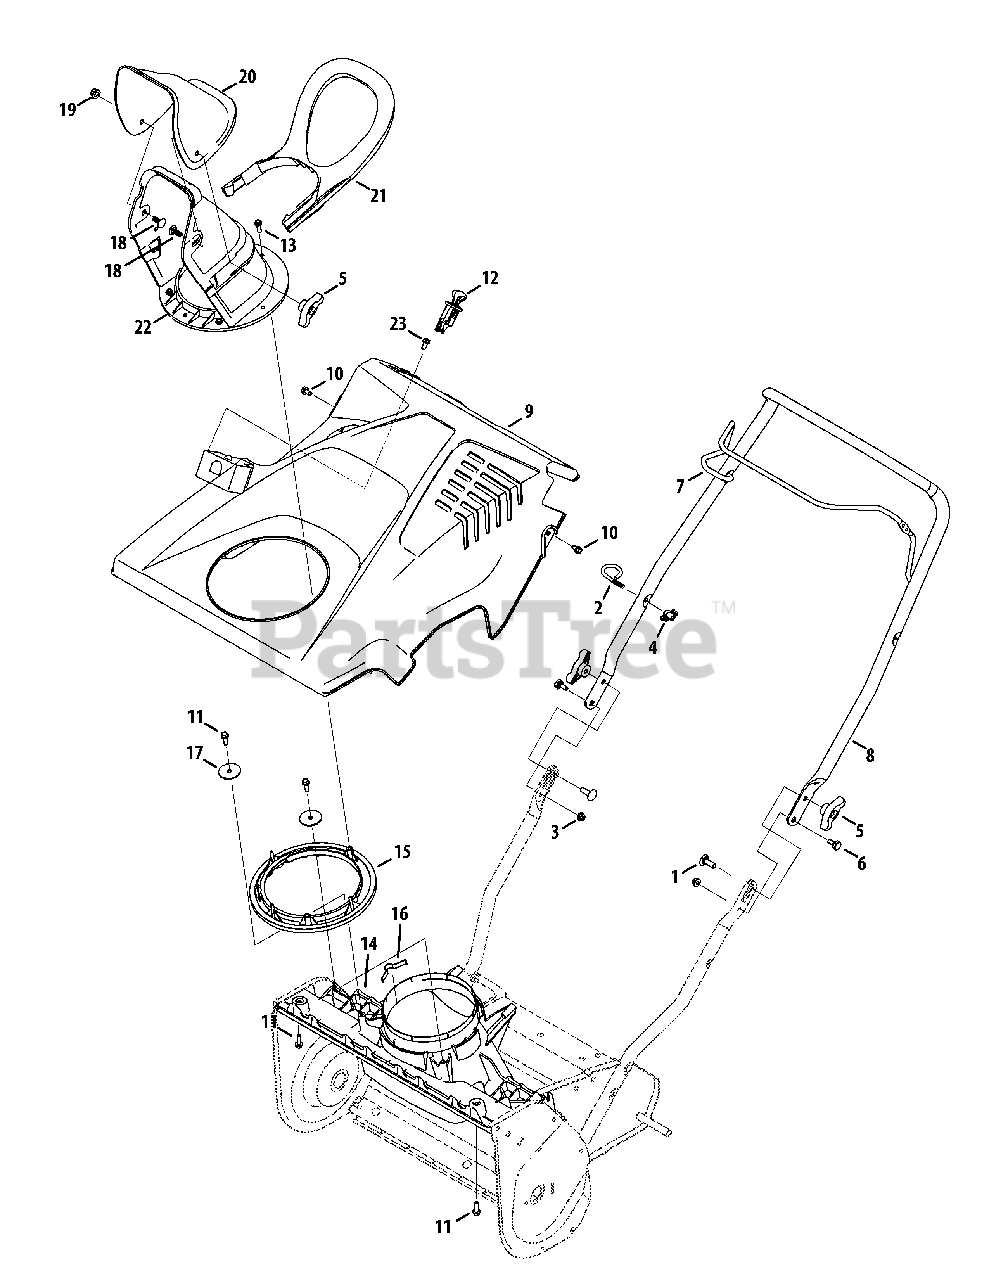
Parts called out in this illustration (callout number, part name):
1	Carriage Bolt 5/16-18 x 1.0
3	Hex L-Flanged Nut 1/4-20 Gr. F Nylon
4	Handle Knob, 1/4-20
6	Shoulder Screw 1/4-20 x .375 x .148
7	Auger Control
8	Upper Handle
9	Cover Assembly (Black, w/o electric start)
9	Cover Assembly (Black, w/elect. start)
9	Cover Assembly (Grey w/elect. Start)
10	Hex Wash S-Tapp Scr 1/4-20 x .50
11	Hex Tapp Scr 1/4 x .75" Lg.
12	Ignition Switch
13	Hex Washer Screw, 1/4-20
14	Chute Adapter
16	Chute Adjustment Spring
17	Flat Washer .28 x 1.51 x .06
18	Carriage Bolt 5/16-18 x .7
19	Flange Locknut 5/16-18 Gr. F, Nylon
22	Lower Chute 5" Dia
23	Hex Washer Screw, 1/4-15 x .50
